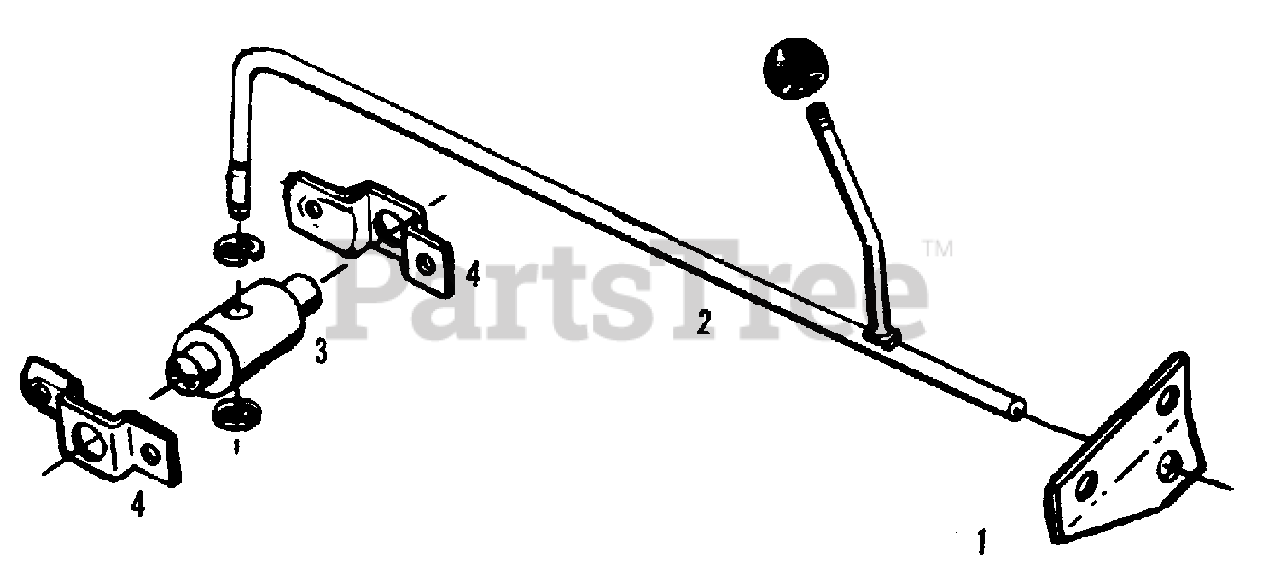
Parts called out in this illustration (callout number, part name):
1	SUPPORT, Gear Shift
2	ROD ASSEMBLY, Shift
2	BALL, Shift Lever
3	PIVOT, Shift Rod
3	RING, External Retaining
4	SUPPORT, Pivot
4	CAPSCREW, 5/16NC x 1-1/4
4	CAPSCREW, 5/16NC x 5/8
4	LOCKWSHER, 5/16
4	NUT, 5/16NC
